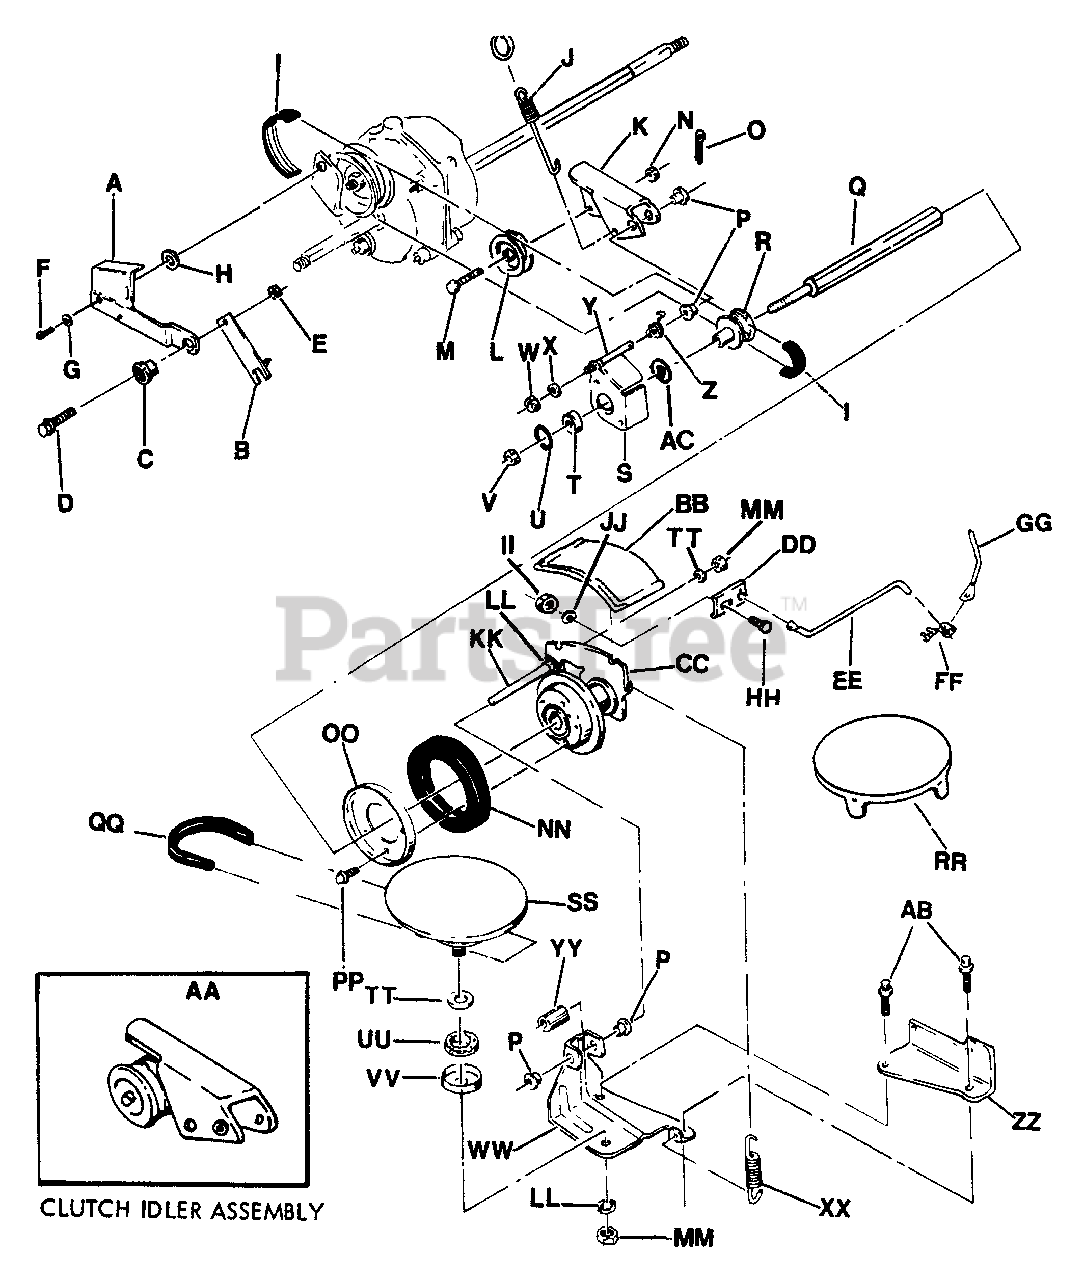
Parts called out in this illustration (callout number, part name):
A	LINK, Differential
B	GUIDE, Lower Belt
C	BUSHING, Differential Link
D	SCREW, 5/16-18 Shoulder
E	NUT, 5/16-24 Hex Center Lock
F	SCREW, 5/16-18 x 3/8" Hex Head Cap, Grade 5
G	WASHER, 5/16 Internal Tooth Lock
H	WASHER, Spring
I	BELT, Poly V
J	SPRING, Clutch
K	ARM, Clutch Idler
L	PULLEY, Idler
M	SCREW, 1/4-28 x 1-3/8" Hex Head Cap, Grade 5
N	NUT, 1/4-28 Hex Top Lock
O	PIN, 3/32 x 3/4" Cotter
P	BUSHING, Flange
Q	SHAFT, Hex
R	PULLEY, Poly V-Belt
S	HOLDER, Bearing (Half)
T	BEARING, Ball (Hex Shaft)
U	O-Ring
V	NUT, 3/8-24 Hex Center Lock
W	NUT, 3/8-24 Hex, Grade 2
X	WASHER, 3/8" Internal Tooth Lock
Y	STUD, Idler
Z	SPRING, Idler (torsion)
AA	ASSEMBLY, Idler Clutch
BB	COVER, Driven Ring
CC	ASSEMBLY, Driven Disc
DD	CONNECTOR, Transfer Rod
EE	ROD, Transfer
FF	CLIP, Transfer Rod Right Arc - 1/4"
GG	LEVER, Speed Control
HH	BOLT, 5/16-18 x 3/4" Square Neck Carriage, Grade 2A
II	NUT, 5/16-18 Hex
JJ	WASHER, 5/16 Split Lock
KK	GUIDE, Thrust Plate
LL	WASHER, 3/8" Internal Tooth Lock
MM	NUT, 3/8-24 Hex, Grade 2
NN	RING, Driven (Rubber Disc)
OO	PLATE, Driven Ring (Tire)
PP	SCREW, #10-24 x 1/2" Hex Washer Self-Tap (Torx)
QQ	BELT, Engine
RR	CAP, Drive Disc
SS	ASSEMBLY, Drive Disc
TT	WASHER, 3/8" SAE Flat
UU	SEAL, Bearing (felt)
VV	SHIELD, Bearing
WW	BRACKET, Deck
XX	SPRING, Wheel Drive
YY	SPACER, Deck Bracket
ZZ	BRACKET, Strap- CV21
AB	SCREW, 5/16-18 x 5/8" Hex Washer Self-Tap
AC	WASHER, .390 I.D. Flat
